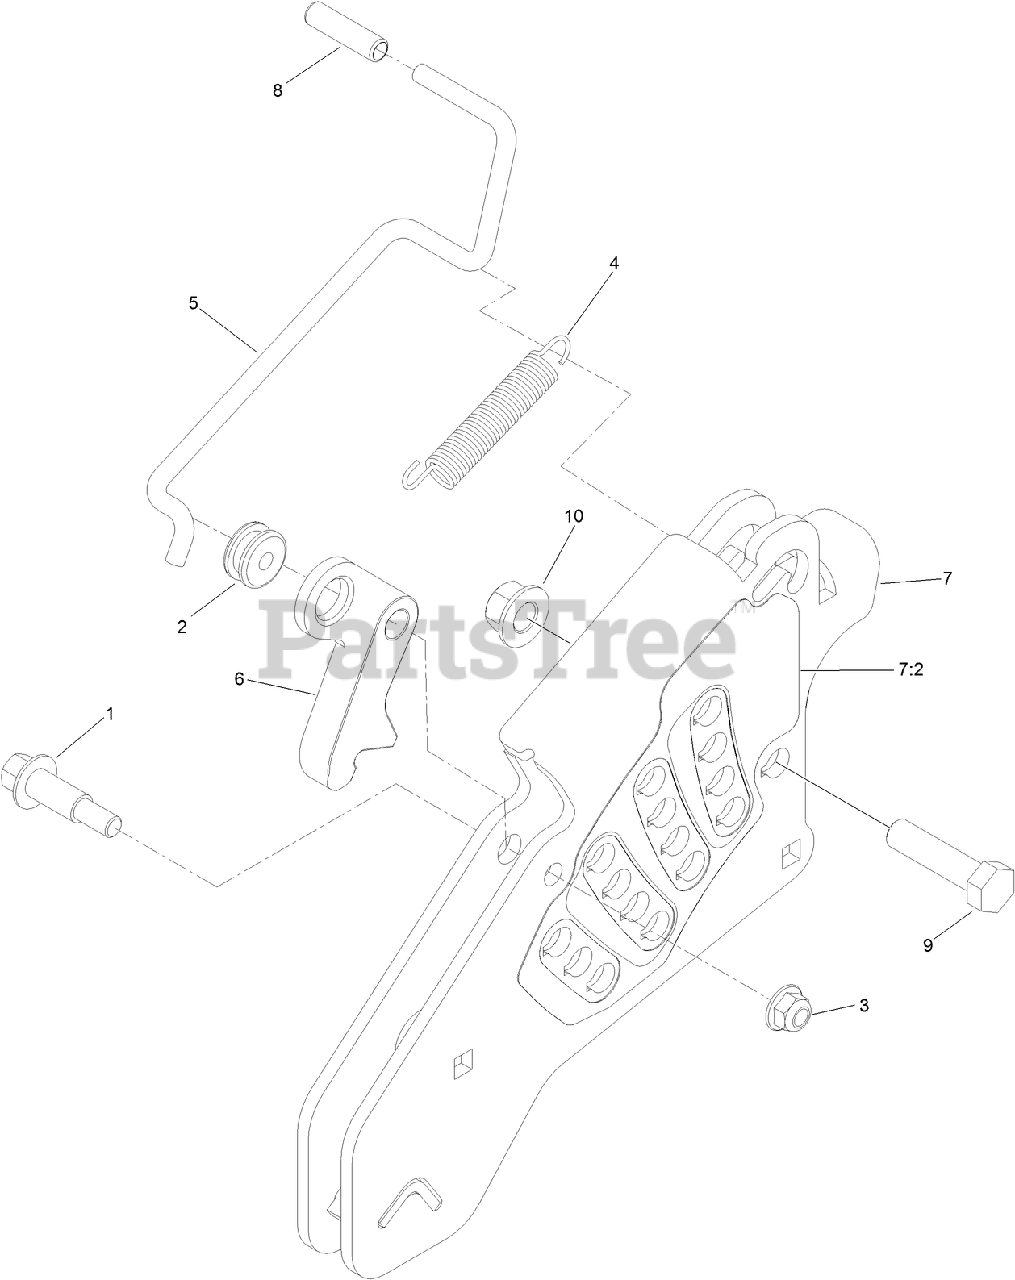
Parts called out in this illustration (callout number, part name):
1	BOLT-SHOULDER
2	GROMMET
3	NUT-HF, NI
4	SPRING-EXTENSION
5	ROD-LOCK, TRANSPORT
6	PAWL-TRANSPORT, HOC
7	HOC PLATE ASM
7:2	DECAL-HOC CE
8	GRIP-LEVER
9	SCREW-HH
10	NUT-LOCK
